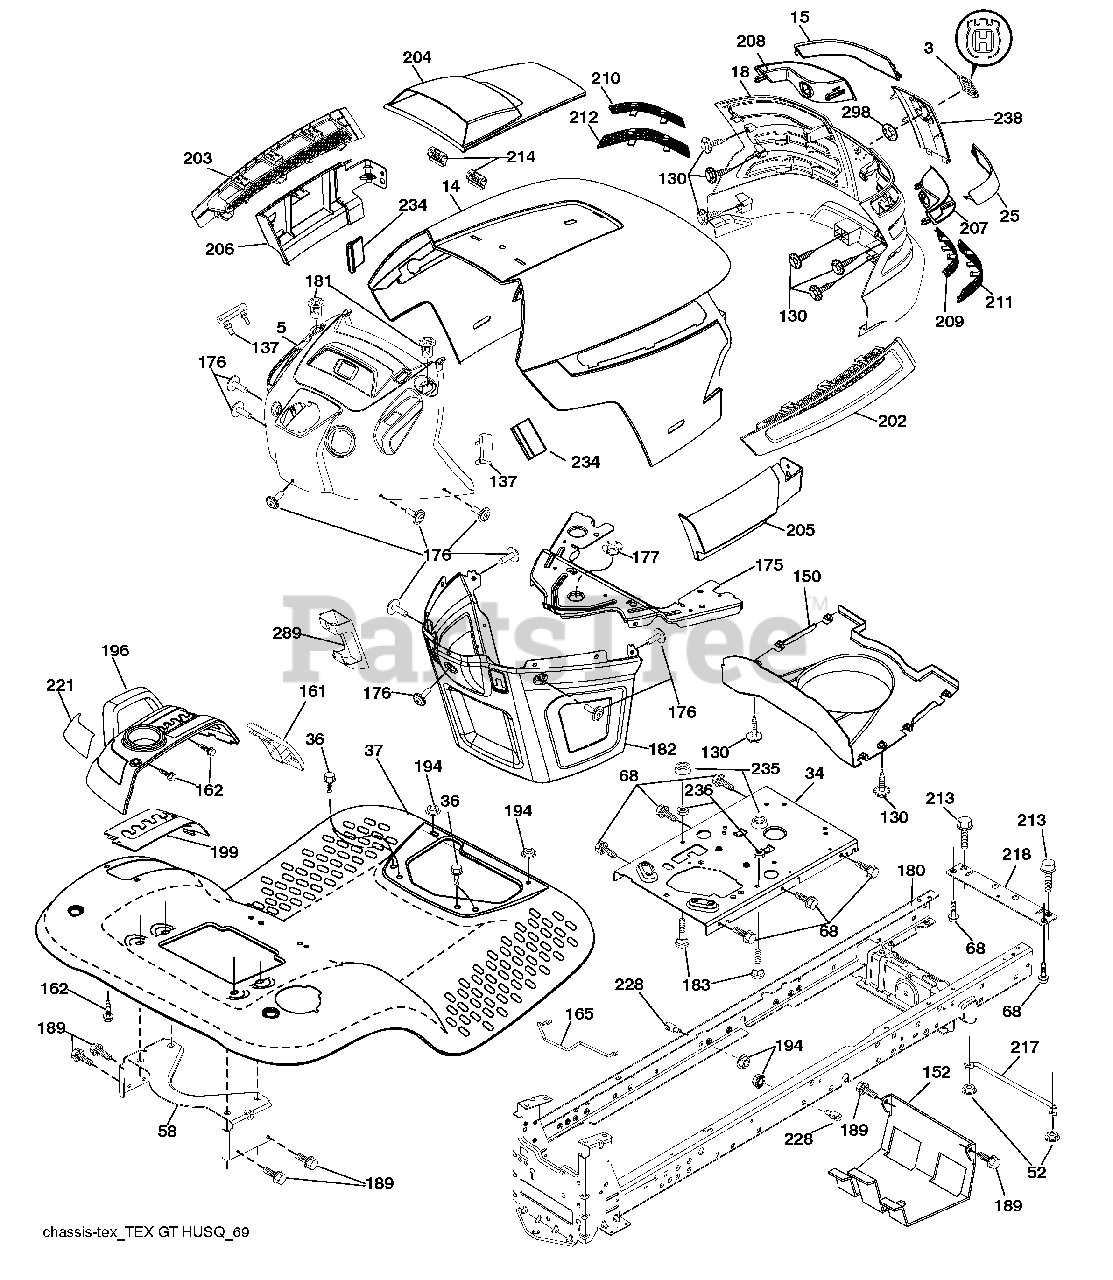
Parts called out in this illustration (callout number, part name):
3	Logo
14	Hood
34	Plate Engine
36	Screw 5/16-18 x 3/4
37	Fender
52	Nut Crown Lock 5/16-18
58	Bracket Fender
68	Screw 5/16-18 x 1/2
130	Screw #10 x 0.750 BOS Thread
137	Bumper Dash
150	Duct Heat Hood
152	Shield Browning/Debris
161	Console Fuel Window
162	Screw Hex Wsh Hi-Lo 1/4 x 1/2
165	Bracket Support Tank
175	Crossmember
176	Screw 10-24 x 5/8 Wshd Qdrx
177	Bushing Steering
180	Chassis
181	Bushing MMT Fender
182	Dash Lower
183	Bolt 5/16-18 x 1-1/4
189	Screw 5/16-18 x 3/4
194	Nut Lock 5/16-18
196	Console Asm. Deck Lift
199	Plate Deck Lift
202	Vent Side Hood RH
203	Vent Side Hood LH
204	Vent Asm Hood Top
205	Skirt Hood Side RH
206	Skirt Hood Side LH
209	Insert Hex Top RH
210	Insert Hex Top LH
211	Insert Hex Bottom RH
212	Insert Hex Bottom LH
213	Bolt Hex Hd 5/16-18 unc x 3/4
214	Clip Retainer
218	Hood Stop X Piece
221	Reflector LH
228	Stud Fastener
234	Bumper Hood
235	Spacer Fender
236	Nut Center Lock 5/16-18 unc
289	Plug Cruise/Phone
